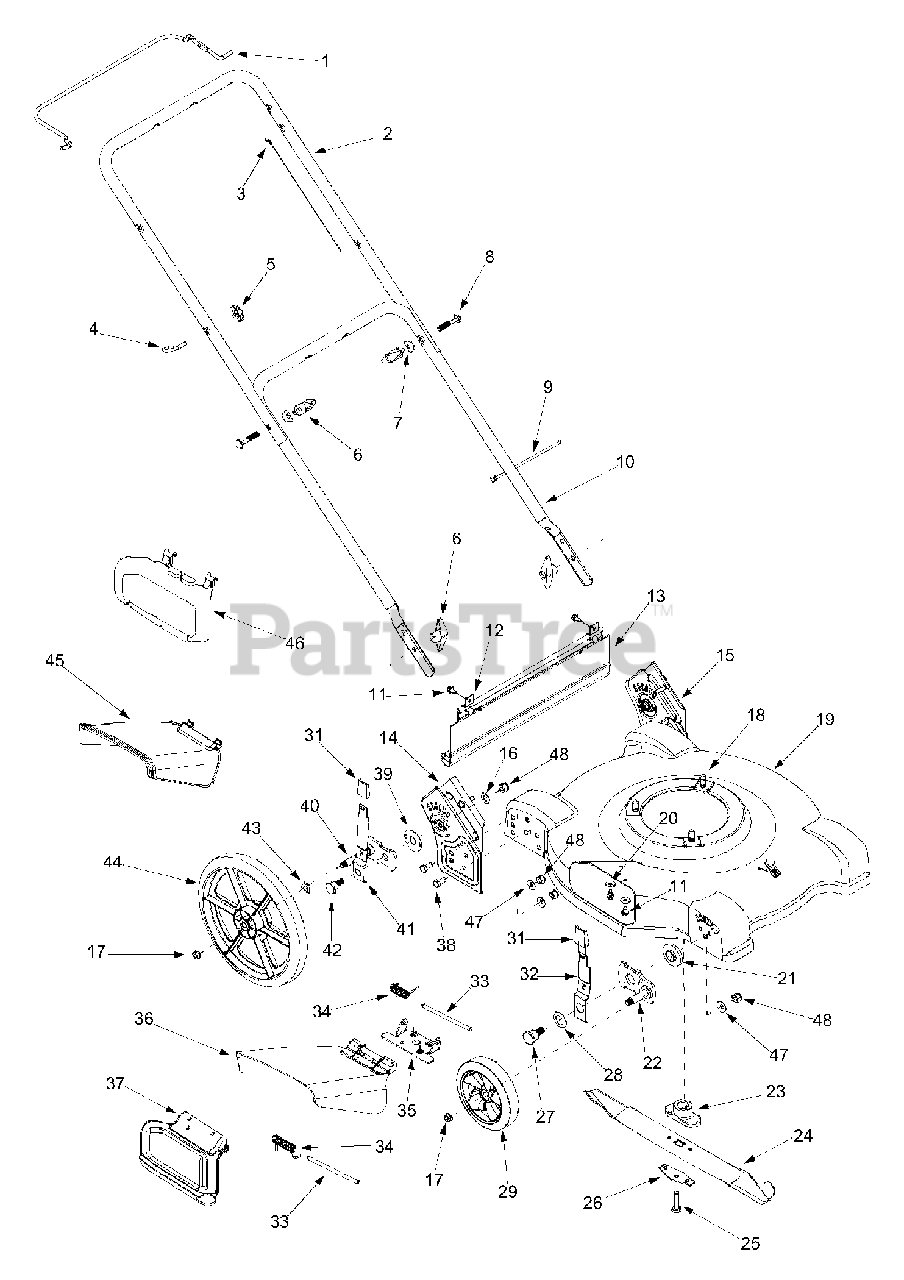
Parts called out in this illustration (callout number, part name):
3	Blade Control Cable - B&S (37.25")
4	Eye Bolt
5	Wing Nut
6	Wing Nut
7	Shoulder Washer .320 ID x .93 OD
8	Carriage Bolt 5/16-18 x 2.0
9	Cable Tie
11	Hex Screw 1/4-14 x .625
12	Hinge Clip
13	Trail Shield
17	Lock Nut 3/8 -16
18	Hex Washer Screw 3/8-16 x 1.0
20	Bell Washer .265 x .75
21	Height Adjuster Bearing
22	Pivot Arm Assembly
23	Blade Adapter
24	Blade 22"
25	Hex Cap Screw 3/8-24 x 1.5
26	Blade Bell Support
27	Shoulder Screw 3/8 - 16 x .302
28	Bell Washer .760 ID x 1.25 OD
29	Front Wheel Assembly 7 x 1.8
31	Height Adjuster Knob
32	Front Spring Lever
33	Hinge Pin
34	Torsion Spring
35	Chute Hinge
36	Side Discharge Chute Assembly
37	Mulching Baffle
38	Hex Cap Screw 3/8-16 x .75
39	Thrust Bearing .688 ID x 1.938 OD
40	Rear Pivot Arm Assembly
41	Rear Spring Lever
42	Shoulder Screw 3/8 - 16 x .442
43	Spring Washer
44	Rear Wheel Assembly 14 x 1.8
45	Snap Discharge Chute
46	Snap Mulching Plug
47	Washer Spacer .401 ID x .870 OD
48	Hex Lock Nut 3/8-16
